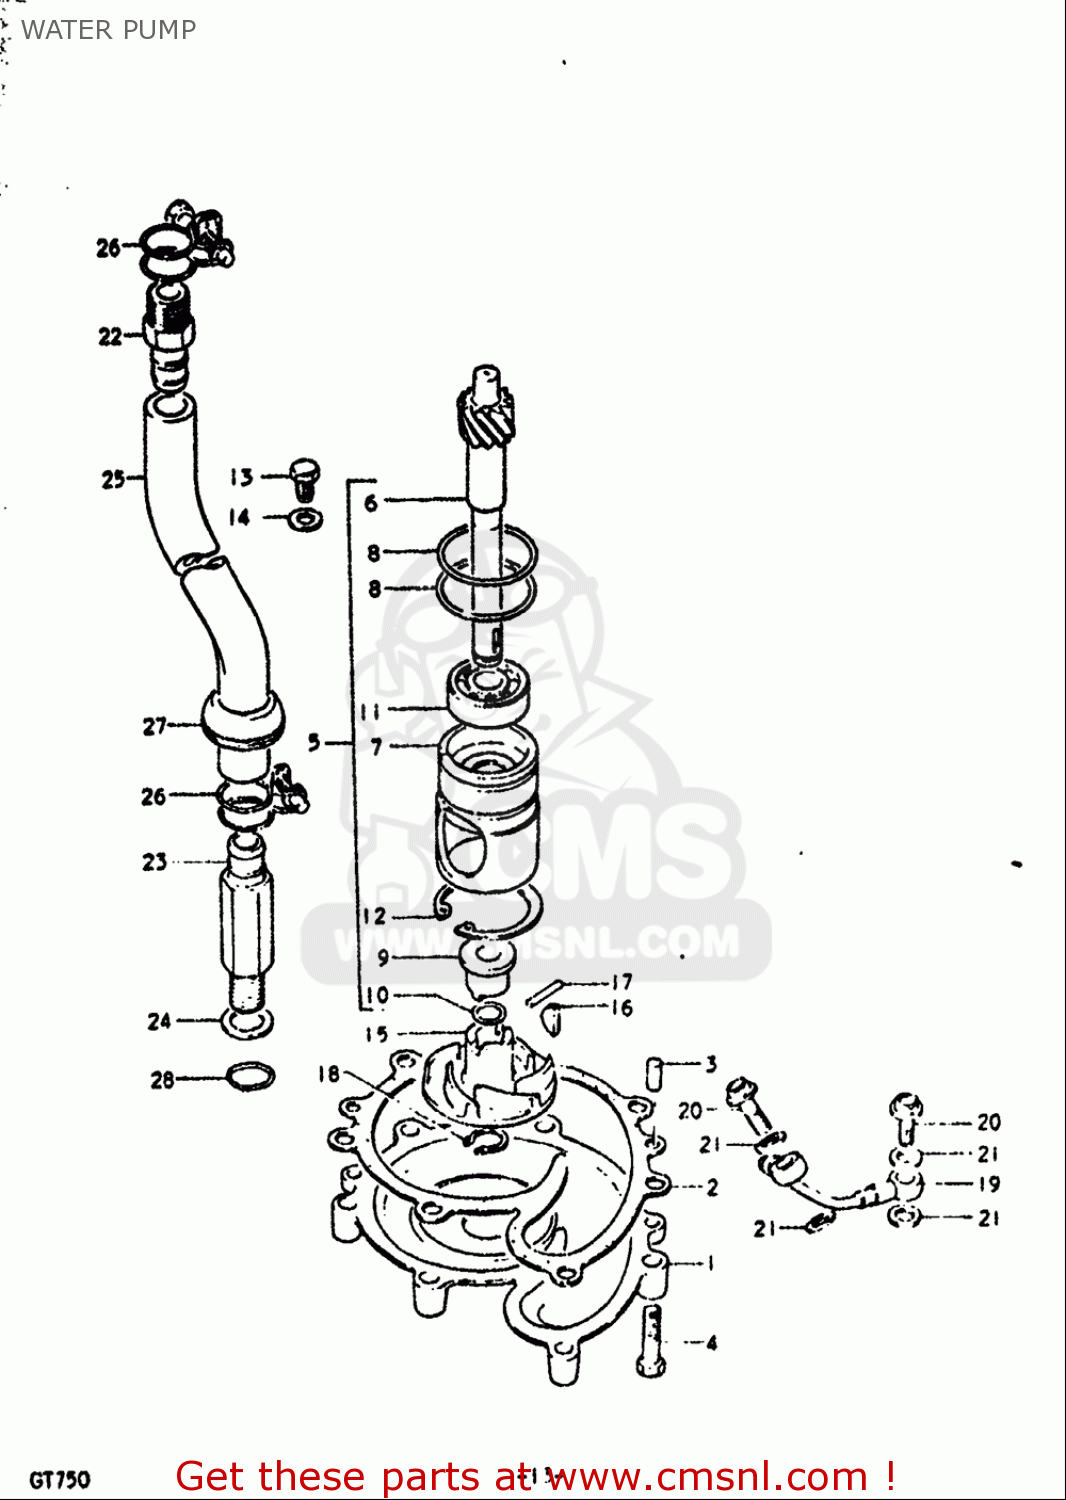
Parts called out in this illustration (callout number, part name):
2	GASKET,WATER PUMP CASE (NAS)
3	PIN
4	BOLT
5	PUMP SET,WATER
7	HOLDER,WATER PUMP DRIVEN SHAFT
8	O RING(D:1.9,ID:32.7)
9	SHEET,WATER PUMP SEALING
10	O RING(D:1.3,ID:9.6)
11	BEARING
12	CIRCLIP
13	BOLT
14	WASHER
16	KEY
17	PIN,SPRING(3X16)
18	CIRCLIP
20	UNION BOLT
21	GASKET(6.2X11X1).2 (NAS)
24	GASKET(14X19.2X2) (NAS)
25	HOSE(13X20)
26	CLAMP
28	O RING(D:2.4,ID:11.8)
